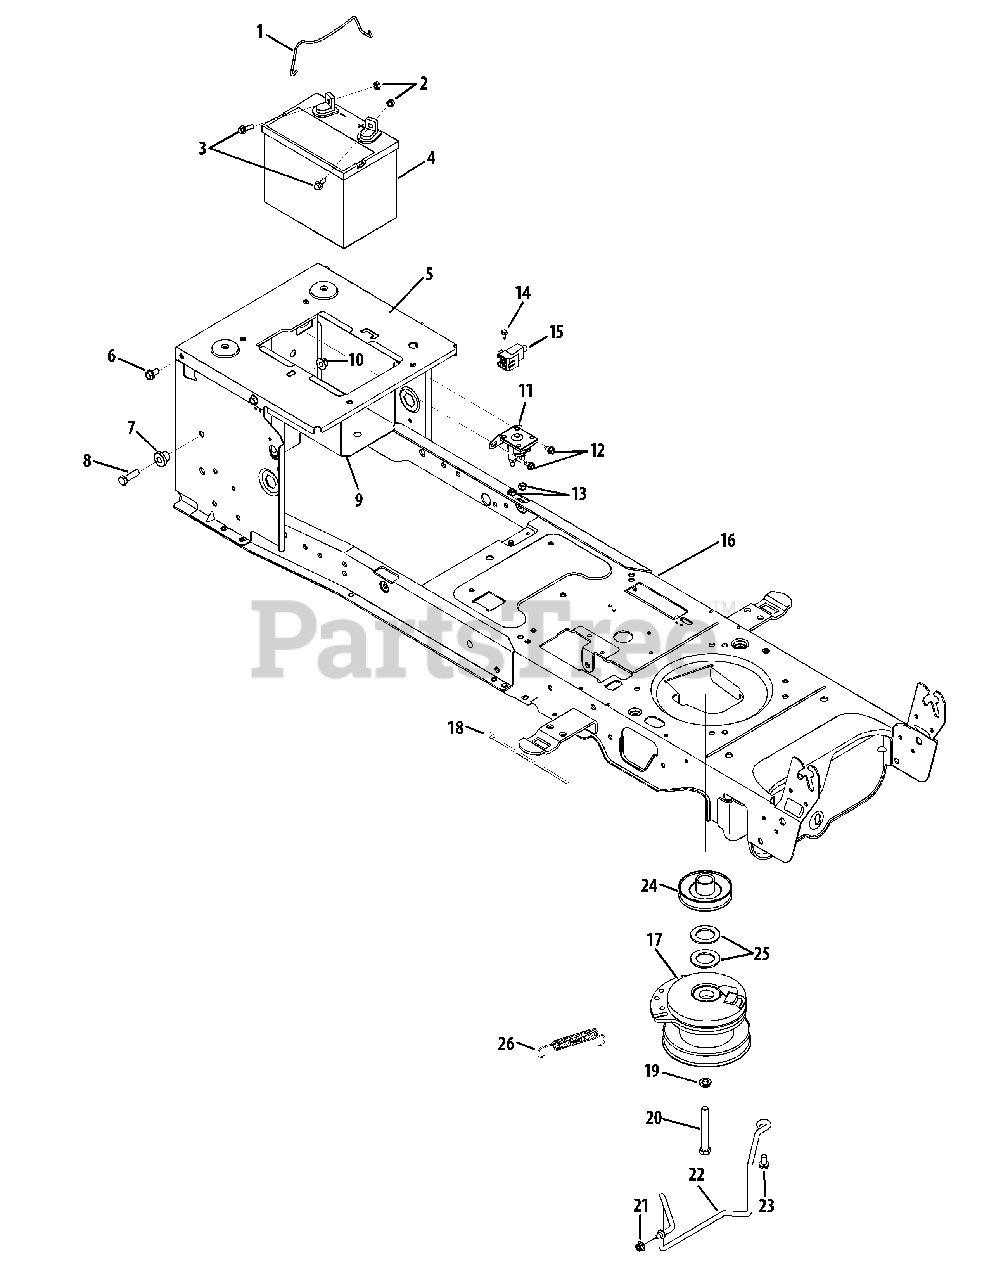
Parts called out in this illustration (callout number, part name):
1	Battery Hold Down Rod
2	Sems Hex Nut 1/4-20
3	Hex Hd. Flg. Screw. 1/4-20 x .75 Gr. 5
4	Battery
5	Seat Frame Bracket
6	Hex Wash Hd. Tapp Screw. 5/16-18 x .75
7	Shoulder Spacer .38 x 1.0 x .70
8	Hex Bolt 3/8-16 x 1.25
9	Battery Tray
10	Flange Lock-Nut 3/8-16 Gr. F Nylon
11	Solenoid
12	Hex Wash HD Tapp Screw 1/4-20 x .375
13	Hex L-Flanged Nut 1/4-20 Gr. F Nylon
14	Shoulder Screw #10-32 x .50
15	Switch, Interlock
16	Lower Frame Assembly
17	Electric PTO Clutch (54")
18	Cable Tie
19	Lockwasher 7/16 ID
20	Hex Cap Lock Screw 7/16-20 x 3.5 Gr. 5
21	Flange Locknut 5/16-18 Gr. F, Nylon
22	Keeper Rod (50" & 54")
23	Hex Wash Hd. Tapp Screw. 5/16-18 x .75
24	Engine Pulley
25	Flat Washer 1.03 ID x 1.64 OD x .095
26	Ext. Spring .5 OD x 5.52" Lg. (50" & 54")
